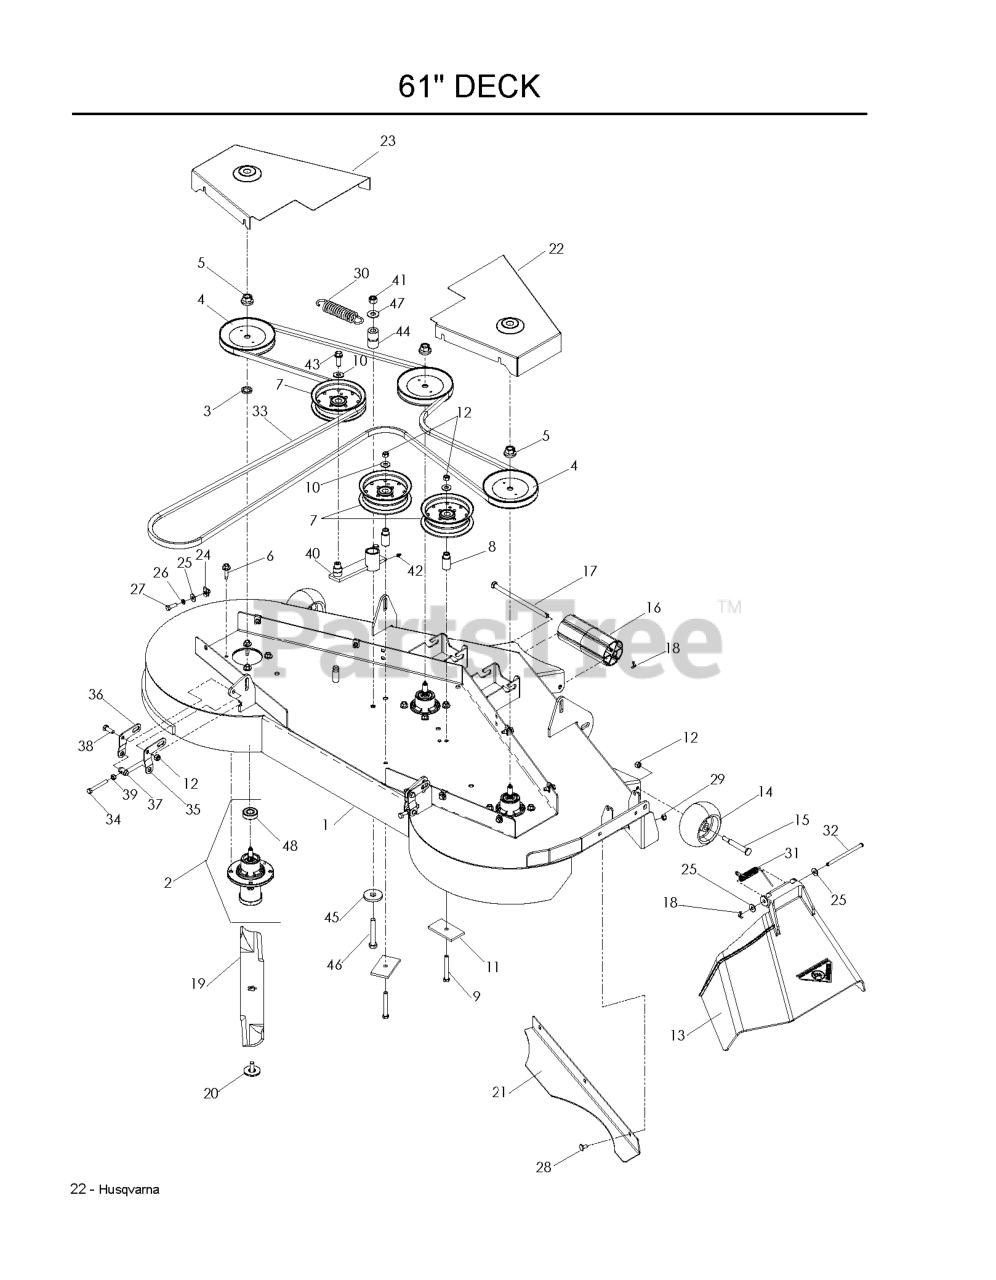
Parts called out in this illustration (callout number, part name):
1	DECK.SVC.W/DECALS.61".EZ.ORANG
2	MANDREL.DECK.ASSEMBLY
3	WASHER-SPACER
5	LOCKNUT - 9/16
6	WASHER HEAD SCREW
7	PULLEY, IDLER
8	IDLER BUSHING
9	HCS 3/8C X 3
10	WASHER 3/8 FLAT
11	SUPPORT PLATE
12	NUT 3/8-16 NYLOC
13	DISCHARGE CHUTE 61"
14	GAUGE WHEEL
15	SHOULDER BOLT 1/2X2-5/8 ZD SPE
16	NOSE ROLLER 48"
17	NOSE ROLLER ROD
18	RP_COTTER PIN 1/8 X 3/4
19	BLADE, 21"
20	BLADE BOLT ASSY-7/16" TB REPL
21	CONFINEMENT PLATE 61
22	BELT SHIELD, RH ORANGE
23	BELT.SHIELD.LH.ORANGE
24	U-CLIP 5/16-18 NUT RETAINER
25	WASHER 5/16 FLAT
26	WASHER.LOCK.HVY.HLCL.SPR.5/16
27	HCS 5/16C X 1
28	CARRIAGE BOLT 5/16C X 5/8"
29	NUT 5/16 NYLOC
31	SPRING - TORSION
32	PIN-CLEVIS 5/16 DIA X 5.19 ZD
33	BELT, DECK
34	HCS 5/16-18 X 2 1/2 TPBLT
35	PITCH, ADJUST, RT
36	PITCH, ADJUST, LT
37	TRUNION, PITCH
38	HCS 3/8-16X1.GRD.5.ZD
39	NUT 5/16C HEX
41	NUT 1/2-13 HEX NYLOC ZD
42	ZERK
43	4CS 3/8C X 1 SERRATED HEAD
44	PIVOT BUSHING
45	WASHER, SUPPORT
46	HCS 1/2C X 3 1/4
47	WASHER 1/2 FLAT
48	BAFFLE LEFT 54
